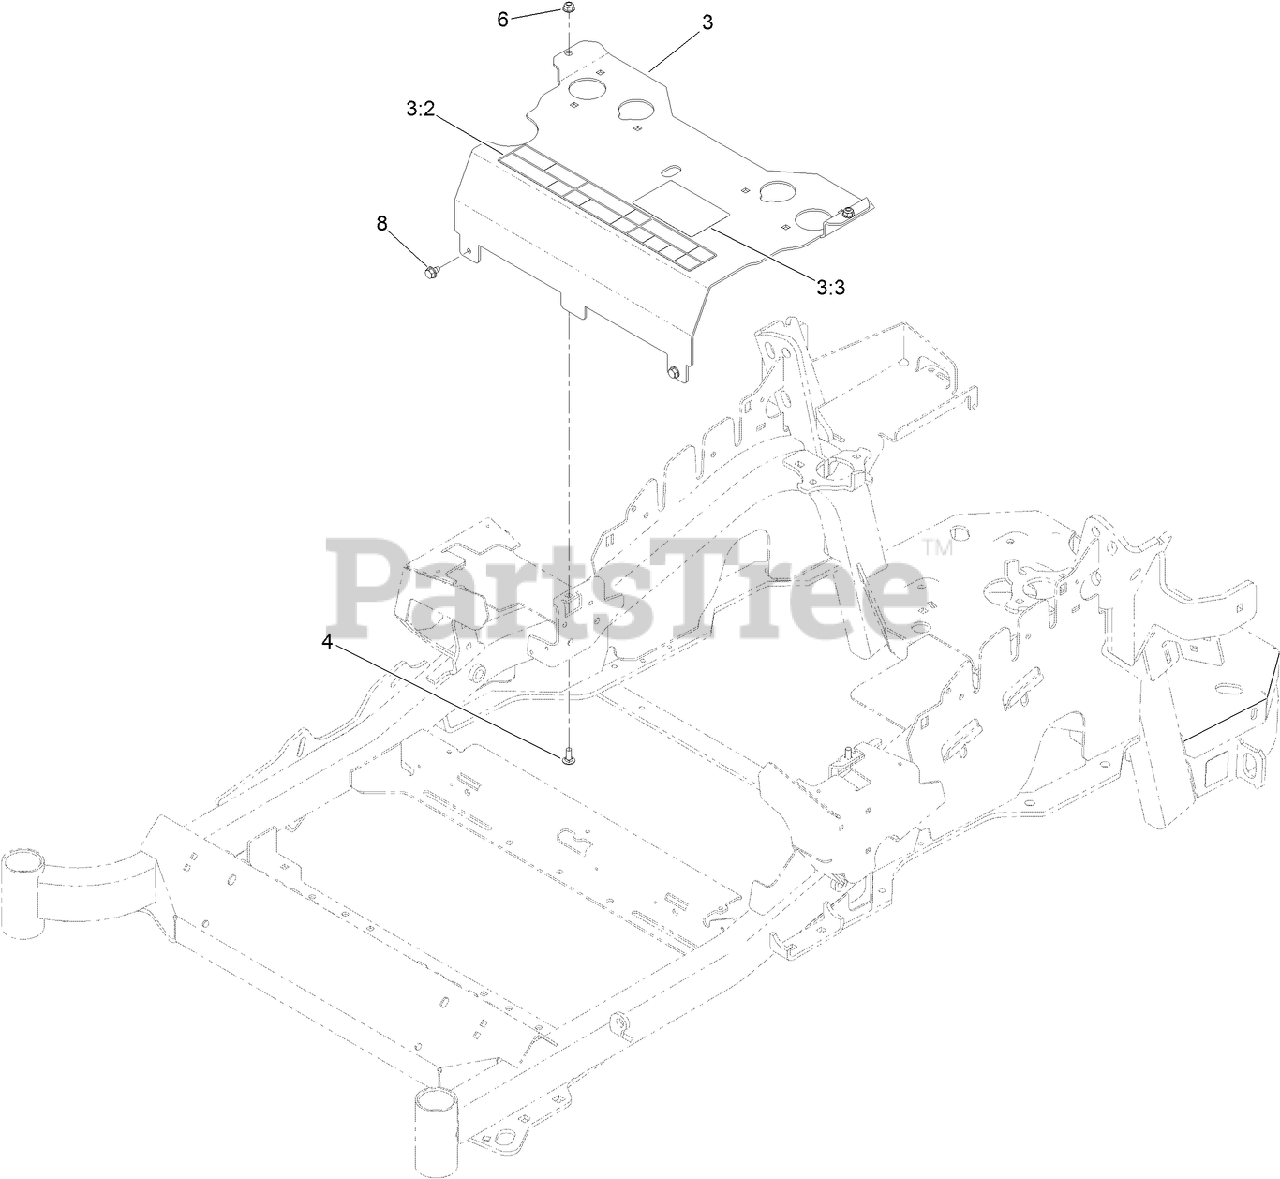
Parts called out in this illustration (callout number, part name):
3	SEAT MOUNT ASM
3:2	DECAL-CONSOLE
3:3	DECAL-SERVICE AID
4	SCREW-CARR
6	NUT-HF, NI
8	SCREW
